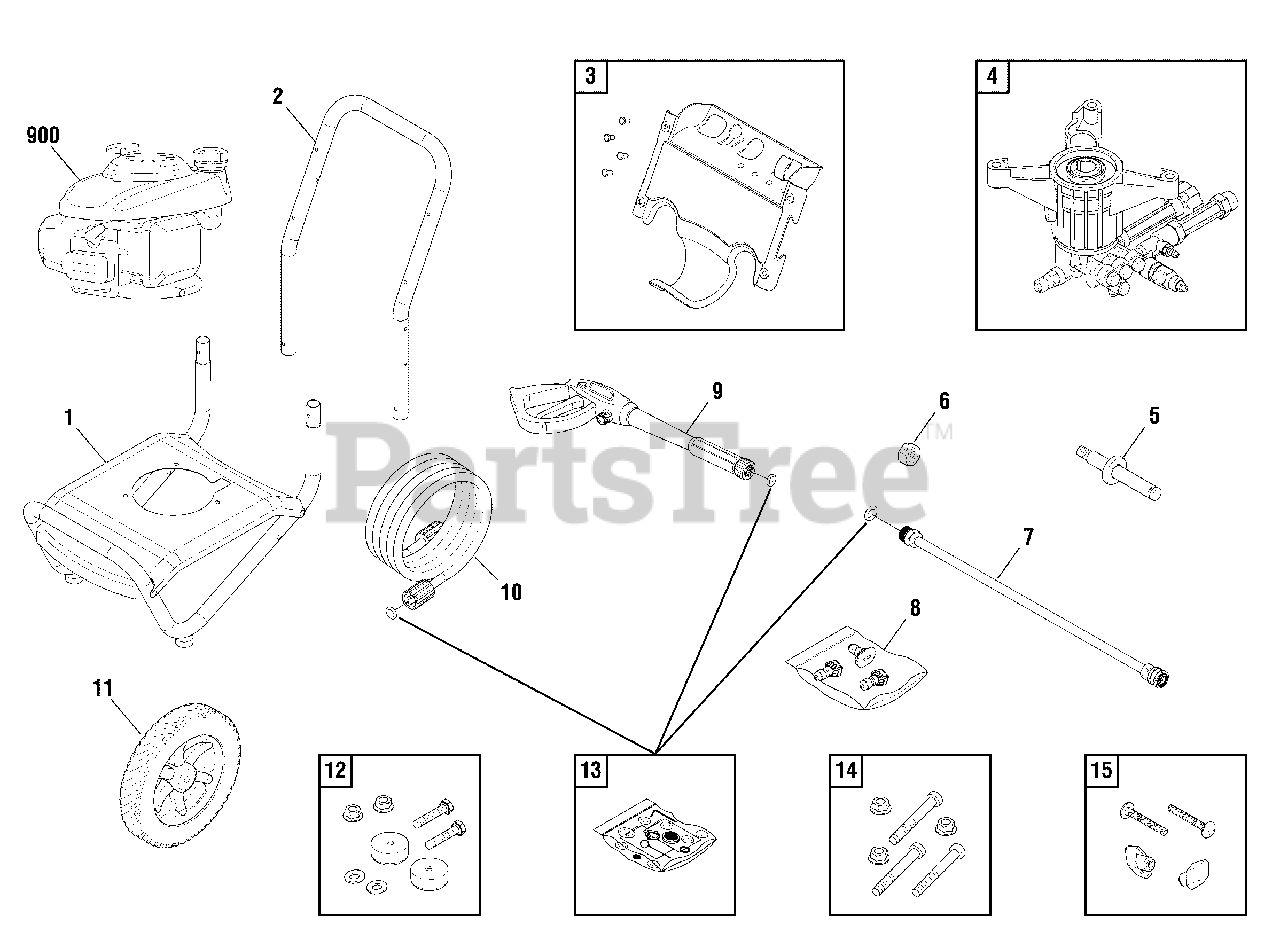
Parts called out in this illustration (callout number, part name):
7	EXTENSION-QC
9	GUN
10	HOSE
12	MOUNT-VIBRATION
14	KIT-HARDWARE PUMP MOUNTING
15	KIT-HARDWARE HANDLE
900	** ENGINE
